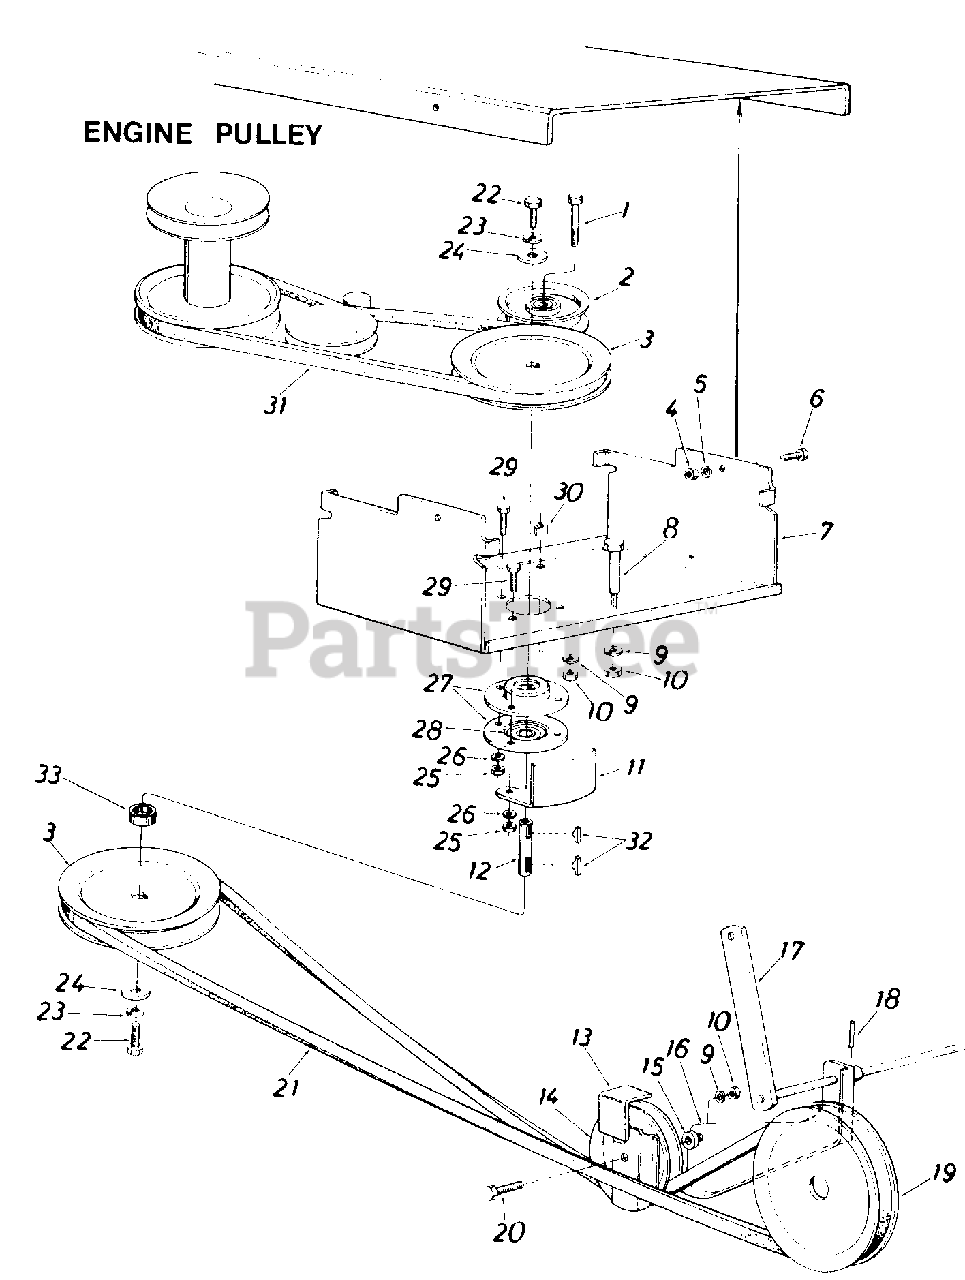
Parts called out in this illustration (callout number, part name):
1	Hex Bolt 3/8-16 x 2.00" Lg.*
2	Fl.-Idler w/Flanges 3-3/4" O.D.
3	5/8" "V"-Pulley .790" I.D. x .650" O.D.
4	Hex ut 3/8-24 Thd.*
5	L.-Wash. 3/8" I.D. Heavy Duty
6	Hex Bolt 3/8-24 x .88" Lg.*
7	Carriage Bracket
8	Shoulder Bolt.498" Dia. x 1 .64
9	L.-Wash. 3/8" I.D.*
10	Hex Nut 3/8-16 Thd.*
13	Belt Separator Plate
14	Fl.-Idler w/Flanges 3.25" O.D.
15	Fl.-Wash. .406" I.D. x 1.25" O.D. x .164
18	Spring Pin Roll 3/16" Dia. x 1.50" Lg.
19	5/8" V-Puliey 1.50" I.D. x 6.50" O.D.
20	Hex Bolt 3/8-16 x 1.75" Lg.*.
21	"V"-Belt 1/2" x 95.0" Lg.
22	Hex Bolt 5/16-18 x .88" Lg. Spec.
23	L.-Wash. 5/16" I.D.*
24	Fl.-Wash. .344" I.D. x 1.125" O.D. x .125
25	Hex Nut 5/16-18 Thd.*
26	L.-Wash. 5/16" I.D.*
27	Bearing Housing 1.85" I.D.
28	Ball Bearing .787" I.D. x 1.85" O.D.
29	Hex Sems Bolt 5/16-18 x .75"
30	Spacer
31	Belt 1/2" Wide x 52" Long
32	Hi-Pro Key 3/16" x 5/8"
33	Spacer-.80" I.D. x 1.0" O.D.
